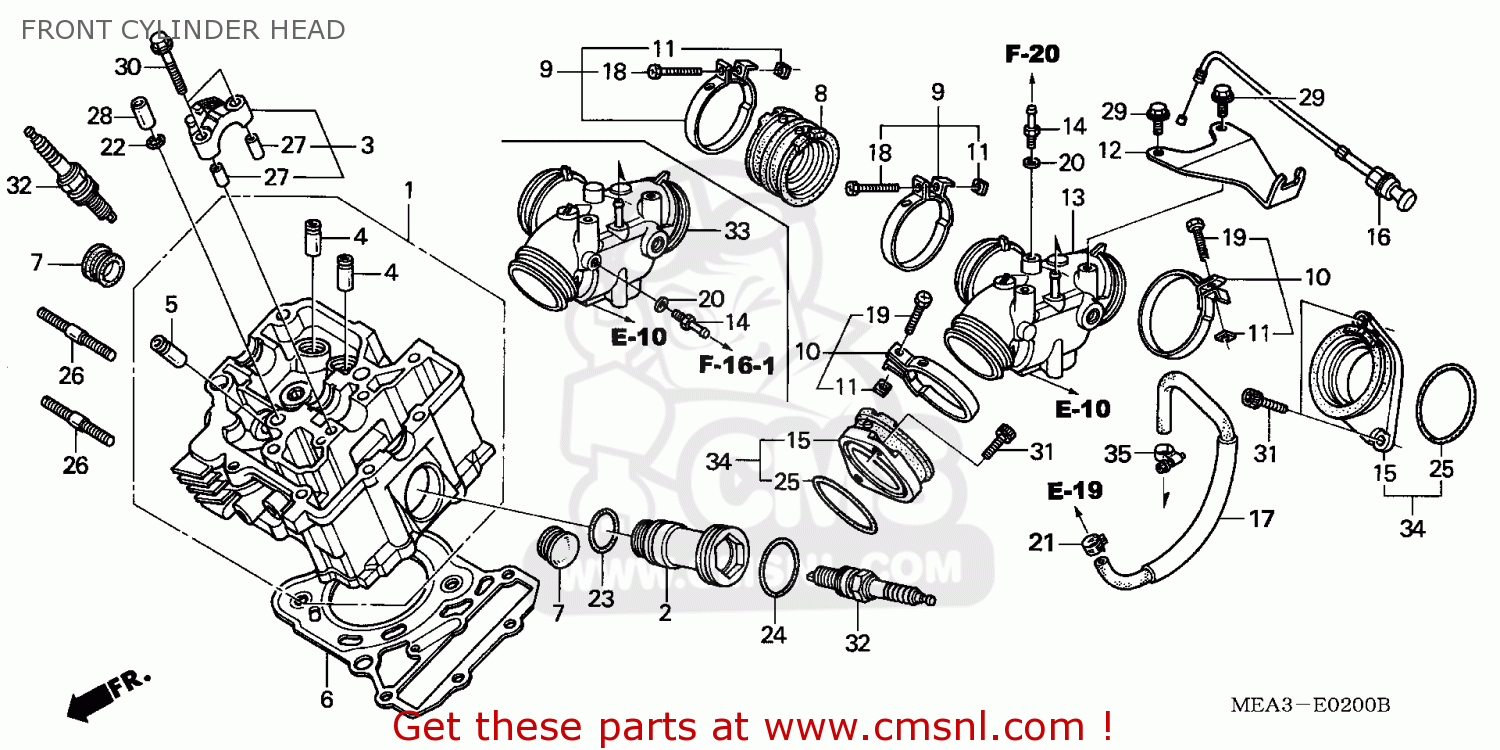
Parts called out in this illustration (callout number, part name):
1	HEAD COMP,FR CYLI
2	SLEEVE,PLUG
3	HOLDER COMP,CAM S
4	GUIDE,IN.VALVE
5	GUIDE,EX.VALVE
6	GASKET,CYLINDER H (NAS)
7	PLUG CAM SHAFT
8	INSULATOR,CARB
9	BAND,INSULATOR
10	BAND,INSULATOR
11	NUT,SQUARE,5MM
12	STAY,CHOKE CABLE
14	JOINT,BOOST
16	CABLE COMP,CHOKE
17	HOSE COMP B,INLET
18	BOLT,RECESSED,5X2
19	BOLT,RECESSED,5X2
20	WASHER 5MM
21	CLAMP D 10.3,TUBE
22	O RING,11.8X2.4
23	O-RING,27.4X2.4
24	O-RING,35.3X2.4
25	O-RING,39.5X2.6
26	BOLT,STUD,8X28
28	DOWEL,PIN,12X20
29	BOLT,FLANGE,6X16
30	BOLT FLANGE 6X38
31	BOLT SOCKET
32	SPARK PLUG,XU20EP
33	MANIFOLD COMP,INL
34	BASE COMP,MANIFOL
35	CLAMP,RADIATOR HO
